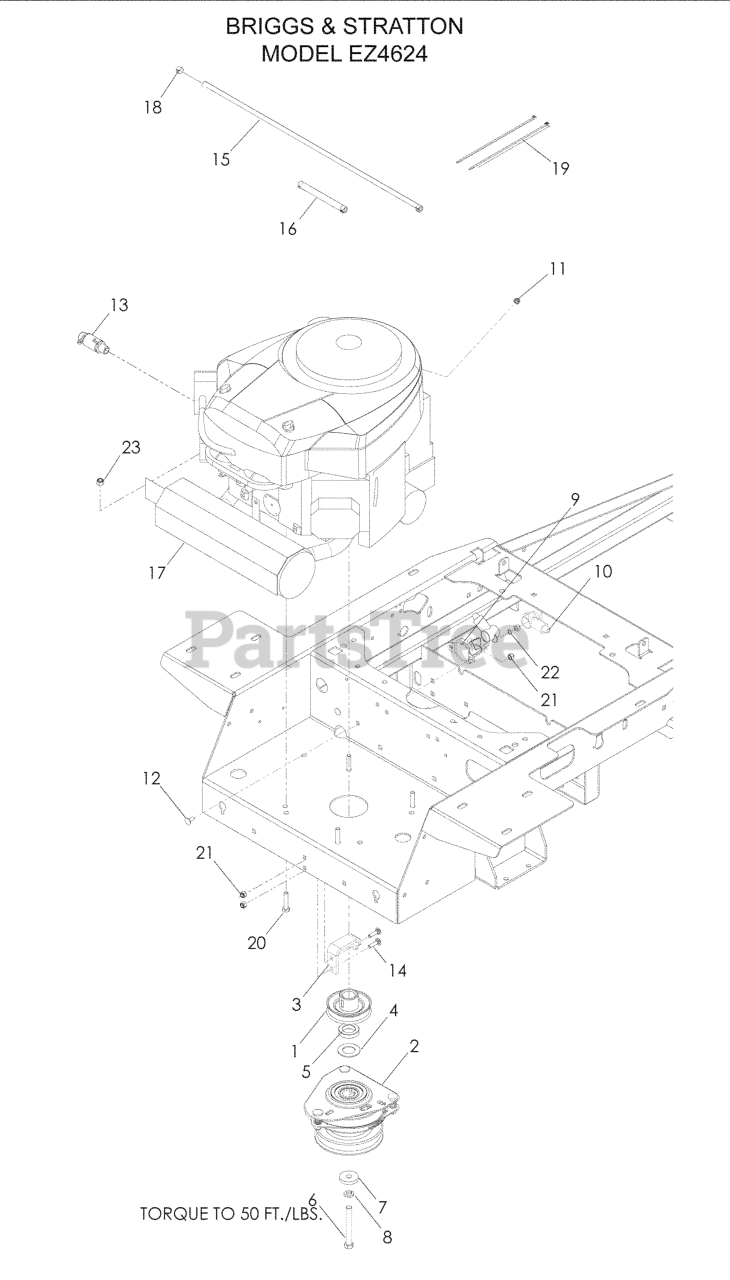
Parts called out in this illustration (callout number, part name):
1	PULLEY, ENGINE
2	CLUTCH, 90 FT/LBS
3	CLUTCH TIE DOWN
6	HCS 7/16-20X3-1/2 GR 5 ZN
7	CLUTCH, WASHER
8	WASHER 7/16 LOCK
11	JAM NUT 1/4C (2 2 PW01)
12	RHSSNB, 1/4-20X5/8
13	OIL DRAIN FITTING
14	RHSNB, 1/4-20 X 1, GR5
15	FUEL LINE 24"
16	FUEL LINE 5"
18	HOSE CLAMP
19	TIE, PLASTIC
20	CAPSCREW 5/16 X 1/1/2 HEX HEAD
21	NUT.1/4-20.HEX.NYLOC.ZD
22	WASHER 1/4 INT TOOTH
23	NUT 5/16 NYLOC
